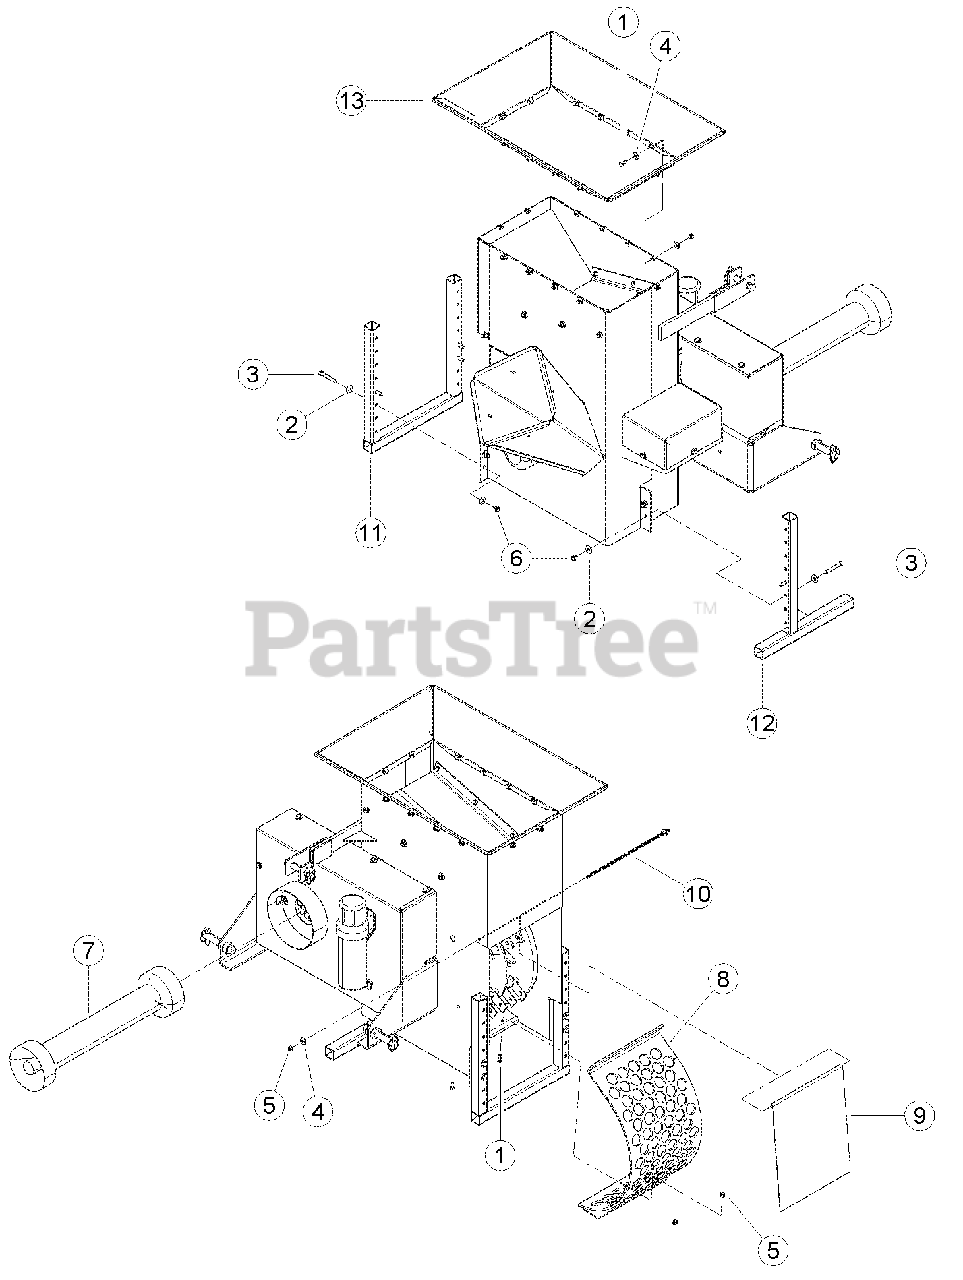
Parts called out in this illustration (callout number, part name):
1	BOLT, 5/16 X 3/4 HEX HD GR5 ZP
2	WASHER, 3/8 FLAT ZP
3	BOLT, 3/8 X 2-1/2 HEX HD GR5 ZP
4	WASHER, 5/16 FLAT ZP
5	NUT, 5/16 NE NYLOCK ZP
6	NUT, 3/8 NE NYLOCK ZP
7	DRIVESHAFT, 540 C/S WS
8	WELDMENT, LARGE SCREEN COARSE
9	DOOR, COMMERCIAL DISCHARGE
10	ROD- DOOR PIVOT
11	WELDMENT, PTO C/S STAND
12	WELDMENT, PTO C/S POST
13	ASSY, HOPPER W/DECALS
